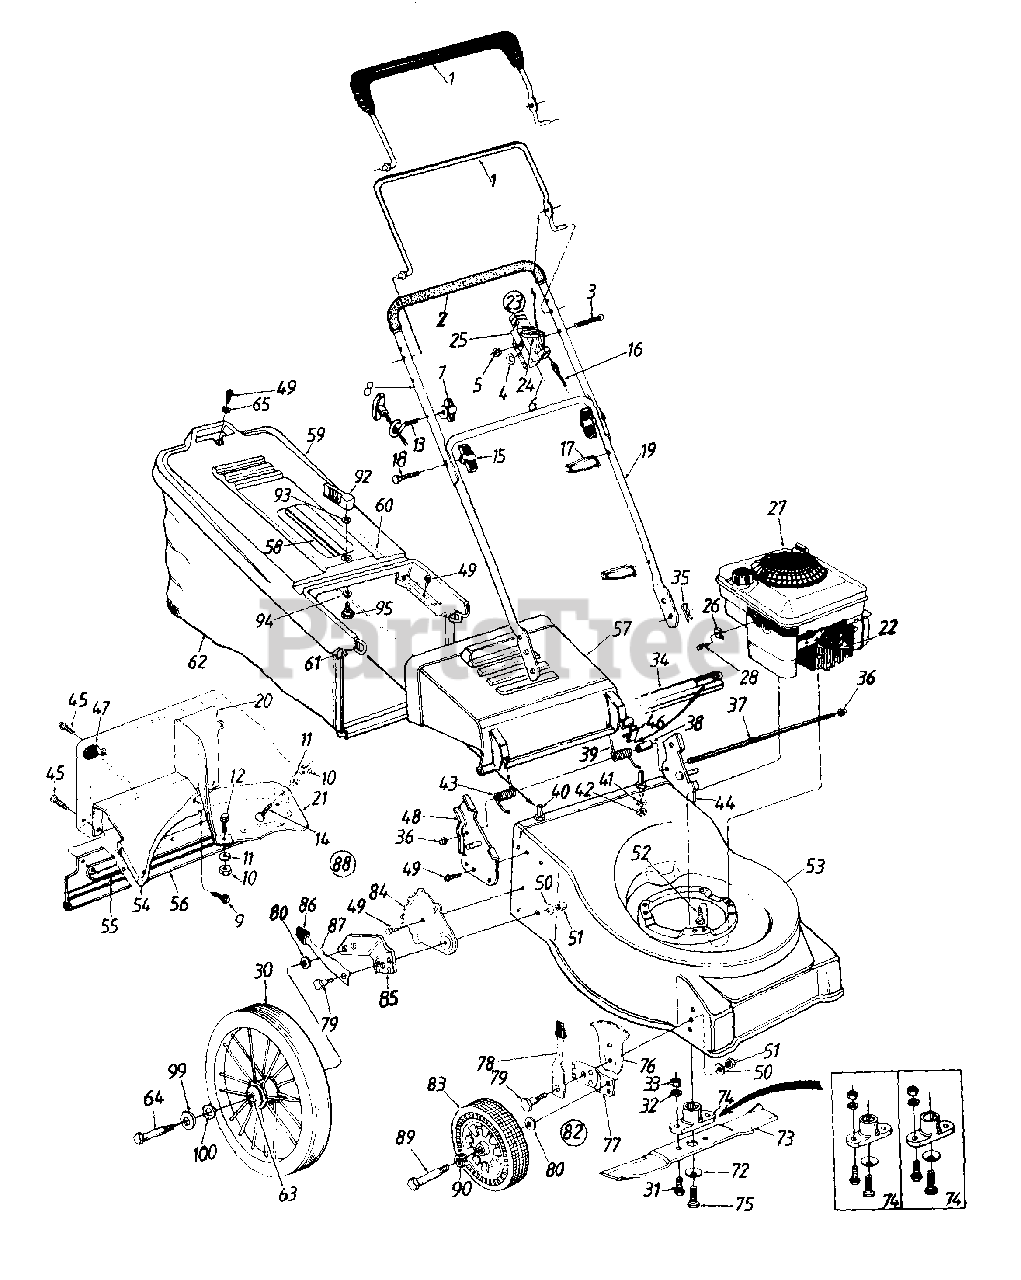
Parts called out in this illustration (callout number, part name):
2	Foam Grip
3	Oval C-Sunk Scr.
4	Spr. Wash..66" I.D.
5	Hex L-Nut 1/4-20 Thd.
6	Throttle Cable - 55"
7	Wing Nut
10	Hex Nut 1/4-20 Thd.
11	L-Wash. 1/4" I.D.
12	Hex Bolt 1/4-20 x .85" Lg.
13	Rope Guide
14	Carriage Bolt 1/4-20 x .5" Lg.
15	Hand Knob
16	Control Cable - 40.5"
17	Cable Tie
18	Curved Hd. Bolt 5/16-18 x 2" Lg.
22	Spark Plug Boot
23	Throttle Box Comp.
24	Throttle Lever
25	Throttle Body
26	Cable Clamp
27	Engine
28	Hex Self-Tap Scr. #10-32 x .62" Lg.
30	Wheel Ass'y. Comp.- Steel Rim
31	Hex Bolt 3/8-24 x 1"
32	L-Wash. 3/8" I.D.
33	Hex Nut 3/8-24 Thd.
34	Seal - Extrusion
35	Int. Cotter Pin 5/16" Dia.
36	Cap Speed Nut
37	Hinge Pin 17.75" Lg.
38	Spacer .255" I.D.
39	Torsion Spring - L.H.
40	Shld. Pin 3/8-24 x 1.43" Lg.
41	L-Wash. 3/8" I.D.
42	Hex Jam Nut 3/8-24 Thd.
43	Torsion Spring - R.H.
46	Deflector Plug
47	Corner Plug
48	Handle Brkt. Ass'y.- R.H.
49	Hex L-Wash. AB-Tap Scr. 1/4 x .62" Lg.
50	Bell-Wash..39" I.D.
51	Hex Nut 3/8-16 Thd.
52	Hex L-Wash. Hd. Scr. 3/8-16 x 1" Lg.
57	Rear Chute Deflector
58	Hardtop Handle
59	Hardtop Bag Cover
60	Rear Catcher Frame
62	Grass Bag
63	Bearing (2 Per Wheel)
64	Shld. Bolt .5 Dia. x 2.62"
65	Fl-Wash..281" I.D.
72	Bell-Wash..46" I.D.
73	21" Blade
74	Blade Adapter Kit
75	Hex Bolt 7/16-20 x 1.5" Lg.
76	Height Adj. Plate
78	Spring Lever Ass'y. w/Knob
79	Shld. Bolt .50" Dia. x .357"
80	Bell-Wash..38" I.D. x .88" O.D.
82	Height Adj. Ass'y. Comp.- R.H.
83	Front Wheel Ass'y. Comp.
84	Index Plate
85	Pivot Bar - R.H.
86	Spring Lever Knob
87	Spring Lever
88	Rear Height Adj. Ass'y. Comp.- R.H.
89	Front Axle Bolt
90	Wave Wash..51" I.D. x .78" O.D.
92	Grass Catcher Locking Knob
93	Internal L-Wash. 1/4" I.D.
94	Wave Washer 3/8" I.D.
95	Shld. Bolt .342" Dia. x .268"
99	Fl-Wash..51" I.D. x 1.373"
100	Spr. Wash..5" I.D. x 1" O.D.
